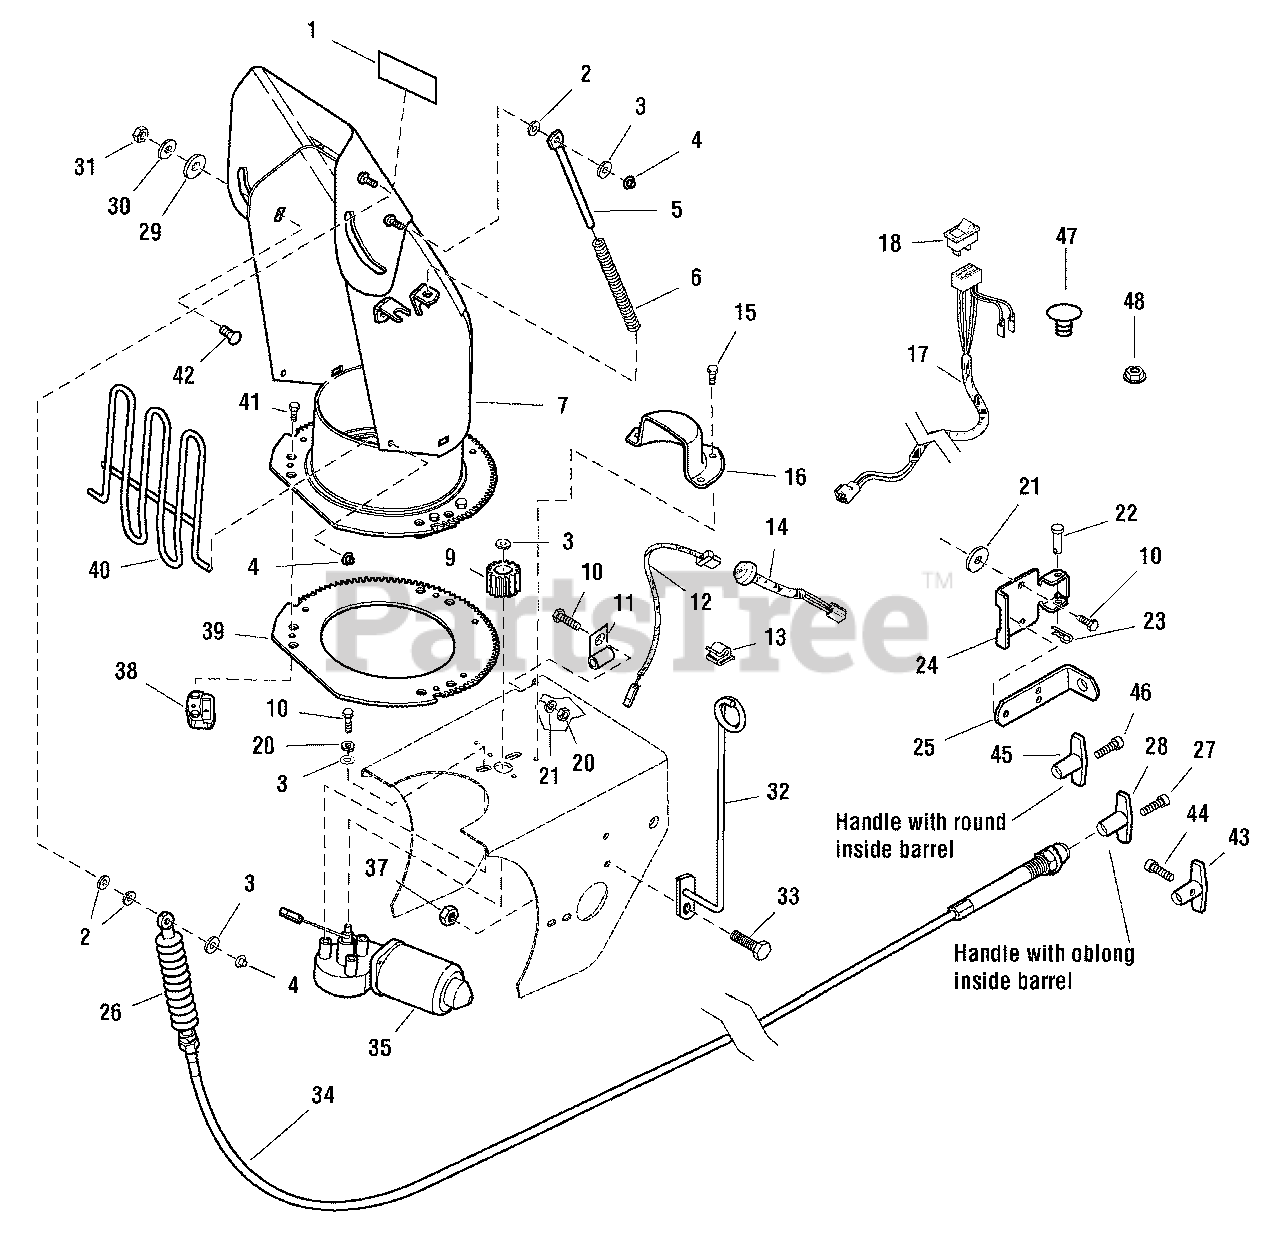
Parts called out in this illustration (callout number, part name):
1	DECAL, Danger
3	CAPSCREW, Hex Washer Head 1/4-20 x 3/4
4	NUT, Push, 1/4
6	SPRING, Compression
7	CHUTE & DEFLECTOR ASSEMBLY
10	CAPSCREW, Hex Head, 1/4-20 x 7/8
11	CLAMP, Wire
12	HARNESS ASSEMBLY
13	CLIP, Wire
14	HARNESS ASSEMBLY, Power Outlet
15	CAPSCREW, Hex Head Taptite, 1/4-20 x 1/2
16	COVER, Pinion
17	HARNESS ASSEMBLY, Spout Rotator
18	SWITCH, Electric
21	WASHER
22	PIN, Flat Head Drilled
23	CLIP, Hair Pin
24	BRACKET, Cable Mount
25	BRACKET, "L"
27	SCREW, Round Head, #8-32
28	HANDLE, "T"
29	WASHER, Special
31	NUT, Hex ESNA Lock, 5/16-18
32	ROD & BAR ASSEMBLY
33	CAPSCREW, Hex Head, 5/16-18 x 1
34	CABLE & KNOB ASSEMBLY
35	MOTOR, Electric
37	NUT, Hex KEPS Washer, 5/16-18
38	HOLD DOWN, Chute
39	GEAR, Chute
40	GUARD & SUPPORT ASSEMBLY
41	CAPSCREW, Hex Washer Head, #10-14 x 5/8
42	CARRIAGE BOLT,5/16-18 x 3/4
44	SCREW, Set, Hex #10-24 x 3/8
45	HANDLE "T"
46	SCREW, Round Head
47	CAP, Plug Black Poly
48	NUT, Hex KEPS Washer
